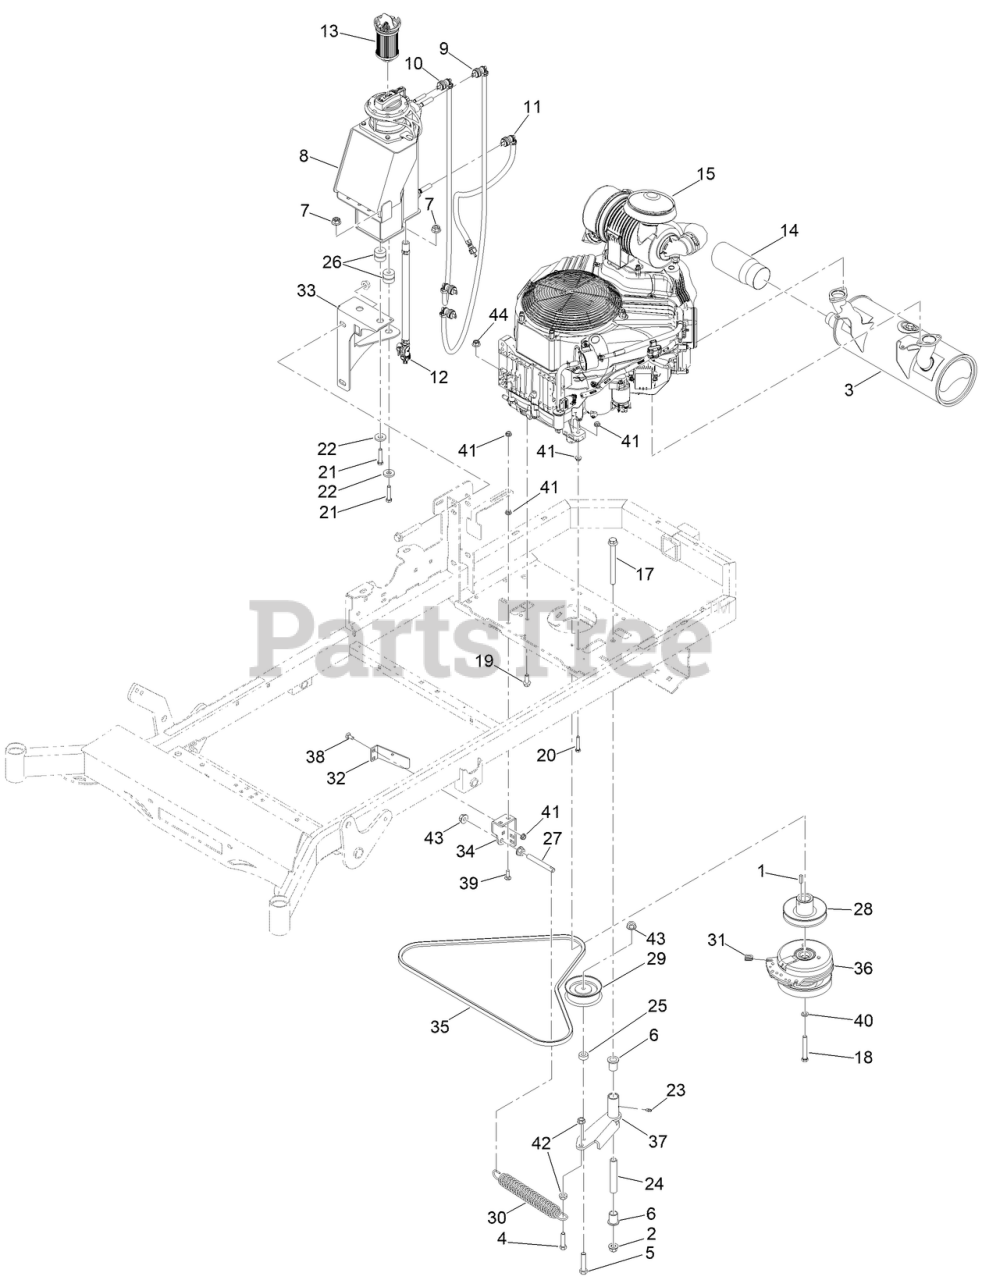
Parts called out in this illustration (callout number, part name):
2	NUT-LOCK
3	MUFF W/SPARK ARRESTER 6.00INOD1.5IN TP
4	SCREW-HH
5	SCREW-HH
6	3/4IN ID X15/16IN OD X 1-1/8IN FLNG BUSH
7	3/8-16 NYLON INSERT FLANGE L/NUT YZ
8	VANGUARD OIL GUARD TANK
9	OIL HOSE ASSY SUPPLY
10	OIL HOSE ASSY SCAVENGE
11	OIL HOSE ASSY VENT
12	OIL FLEX DRAIN HOSE
13	OIL FILTER FOR OIL GUARD
14	MWR CHROME EXHAUST TIP
15	VANGUARD 40HP EFI WITH OIL GUARD
17	1/2-13 X 5-1/2 HEX FLANGE BOLT GR 8 ZY
18	7/16-20 X 3 HEX C/S GR 8 ZC YELLOW
19	SCREW-HH
20	5/16-18 X 1-3/4 HEX C/S GR 5 ZINC YELLOW
21	3/8-16 X 1-3/4 HEX C/S GR 2 ZINC
22	1/2 FENDER WASHER 1-1/4IN OD ZINC
23	1/4IN DRIVE TYPE GREASE FITTING YZ
24	MWR INNER IDLER SPACER
25	MWR PULLEY SPACER
26	OIL GUARD ISOLATOR
27	MWR PUMP IDLER SPRING TENSIONER
28	MWR HYDRAULIC PUMP DRIVE PULLEY (B-BELT)
29	4IN DIESEL AND ECONOMY MWER IDLER PULLEY
30	MWR DECK SPRING
31	MWR CLUTCH ROTATION STOP BRKT SLEEVE
32	MWR CLUTCH ANTI ROTATION BRKT PAINTED
33	MWR OIL GUARD TANK BRKT PAINT
34	MWR PUMP IDLER TENSIONING BRKTPAINTED
35	MWR PUMP BELT XD B X 69.40IN EFF LNGTH
36	WARNER PTO CLUTCH
37	4IN PUMP IDLER PULLEY ARM ASSY PAINT
38	BOLT-CARR
39	BOLT-CARR
40	WASHER-LOCK
42	NUT-HF
43	NUT-HHF
44	3/8-16 HEX FLANGE NUT W/SERR ZINC YELLOW
